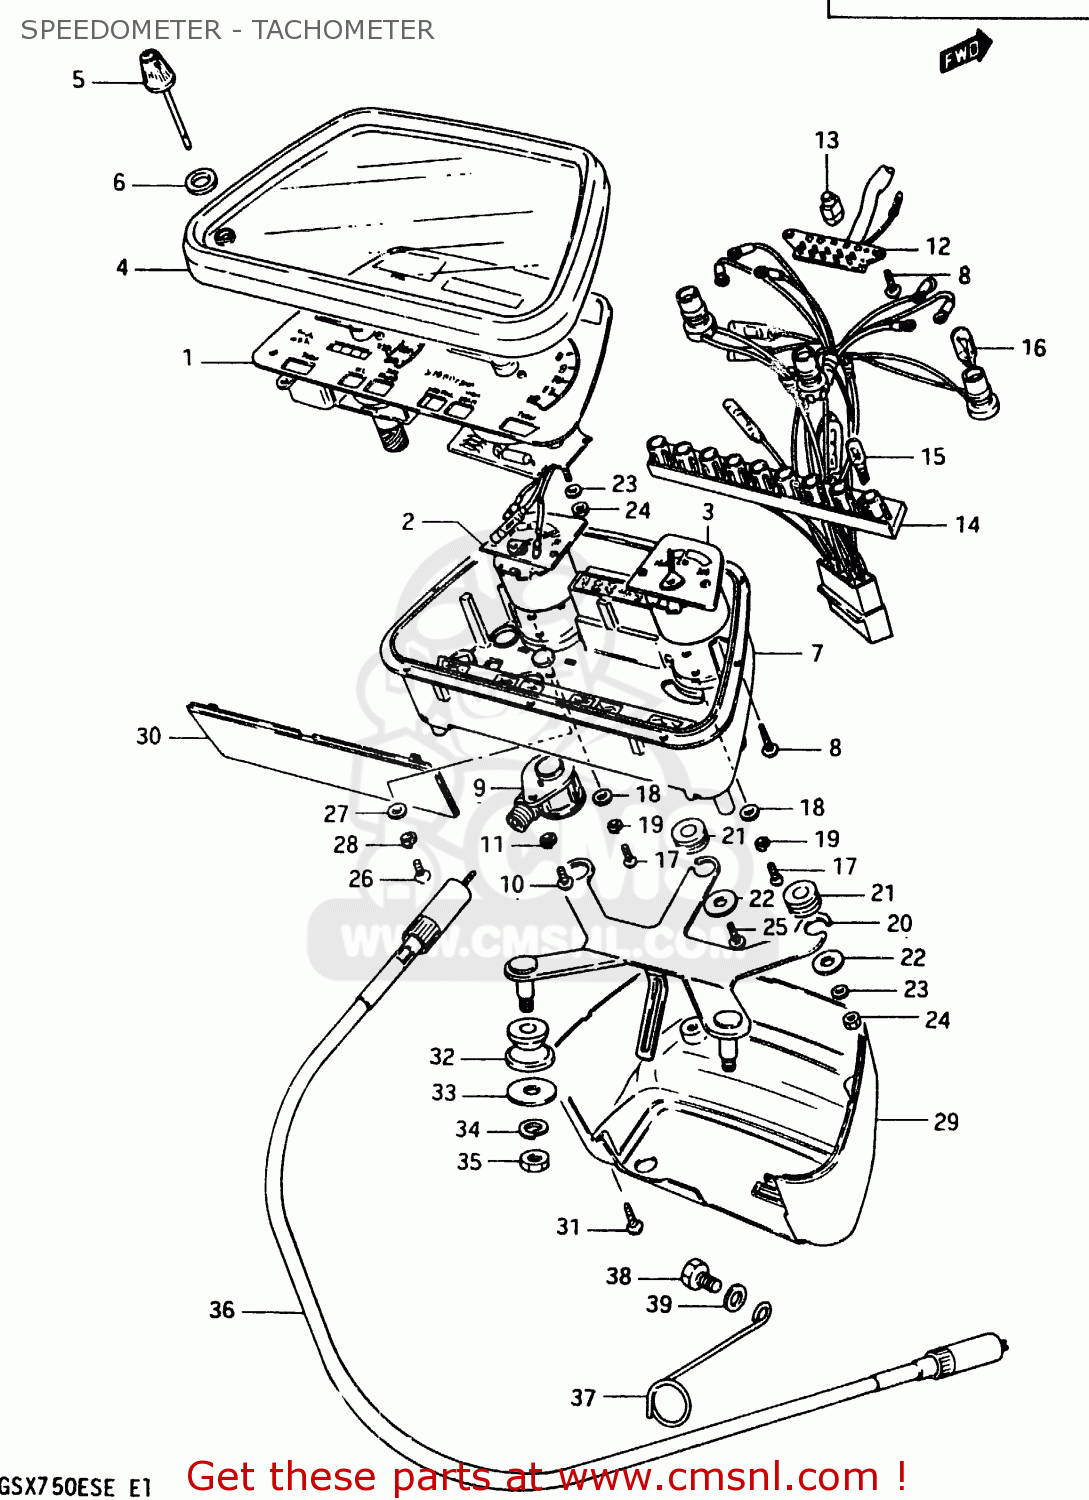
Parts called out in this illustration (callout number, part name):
1	SPEEDO & TACHOMETER (KILO)
2	METER,FUEL
3	4
4	HOOD,METER
5	KNOB,TRIP METER
6	SEAL,TRIP KNOB
7	CASE,METER INNER
8	SCREW
9	GEAR BOX,SPEEDOMETER
10	SCREW 4X10
11	LOCK WASHER
12	SOCKET,GEAR INDICATOR
13	BULB(14V1.12W)
14	SOCKET, METER
15	BULB(12V3W,WB371,T7)
16	BULB(12V3.4W,T10,BF175-01450A)
17	SCREW 3X12
18	WASHER
19	LOCK WASHER
20	BRACKET,METER
21	CUSHION
22	WASHER,COMBINATION METER
23	LOCK WASHER
24	NUT 4MM
25	SCREW
26	SCREW
27	WASHER
28	LOCK WASHER
29	COVER,METER LWR
30	PLATE,COVER
31	SCREW
32	CUSHION,METER BRACKET
33	WASHER (8.5X20X1.6)
34	LOCK WASHER
35	NUT
36	CABLE ASSY,SPEEDOMETER
37	CLAMP,SPEEDOMETER CABLE
38	BOLT, UPPER
39	WASHER
